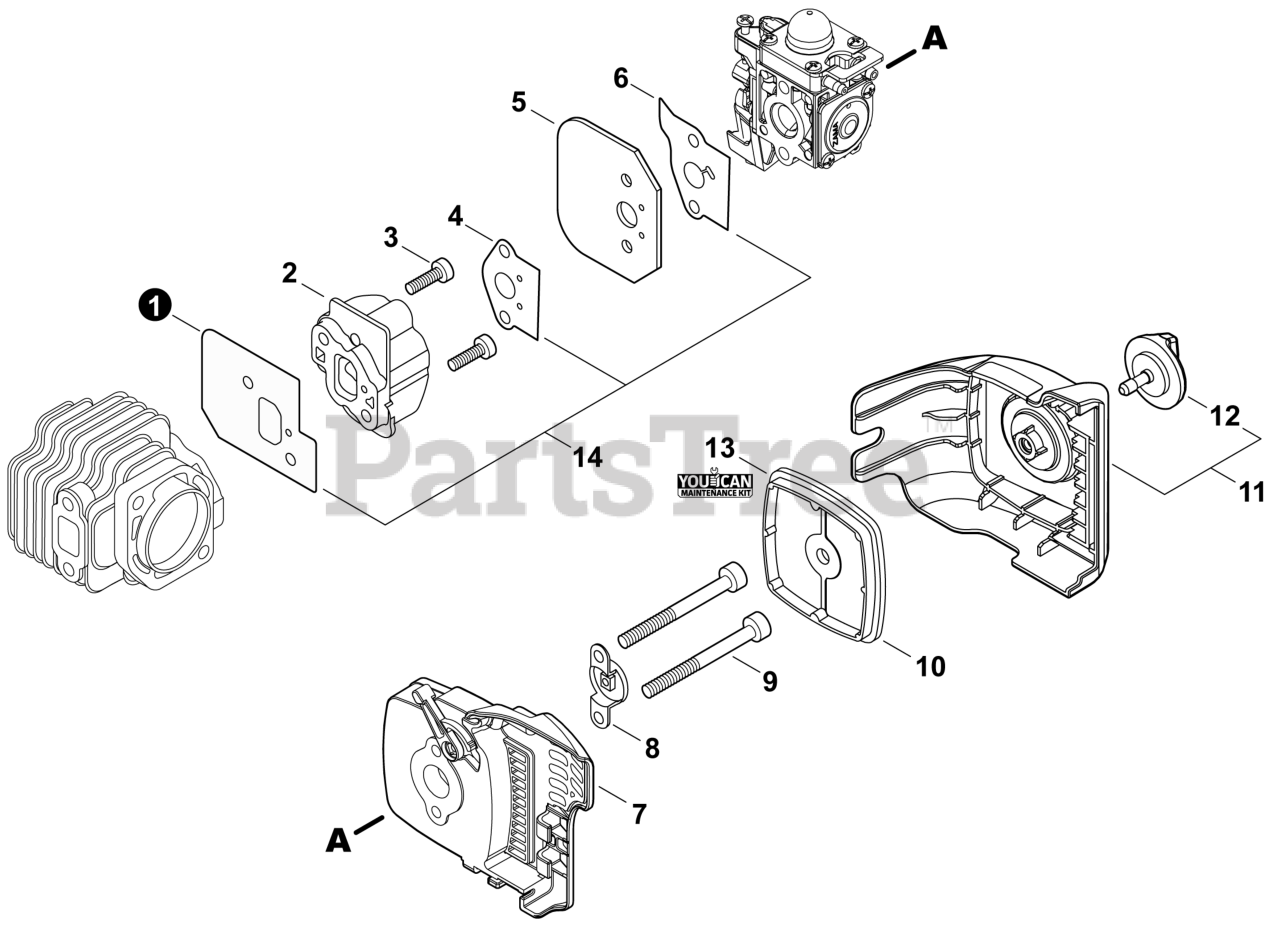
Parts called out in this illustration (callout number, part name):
1	GASKET, INTAKE
2	INSULATOR, INTAKE
3	BOLT, TORX 5x25
4	GASKET, INTAKE
5	PLATE, INSULATOR
6	GASKET, INTAKE
7	CASE, AIR FILTER
8	PLATE, PREVENT
9	BOLT, TORX 5x65
10	FILTER, AIR - DOUBLE LAYER
11	COVER SET, AIR FILTER
12	THUMBSCREW
13	TUNE-UP KIT - YOUCANT
14	GASKET KIT
